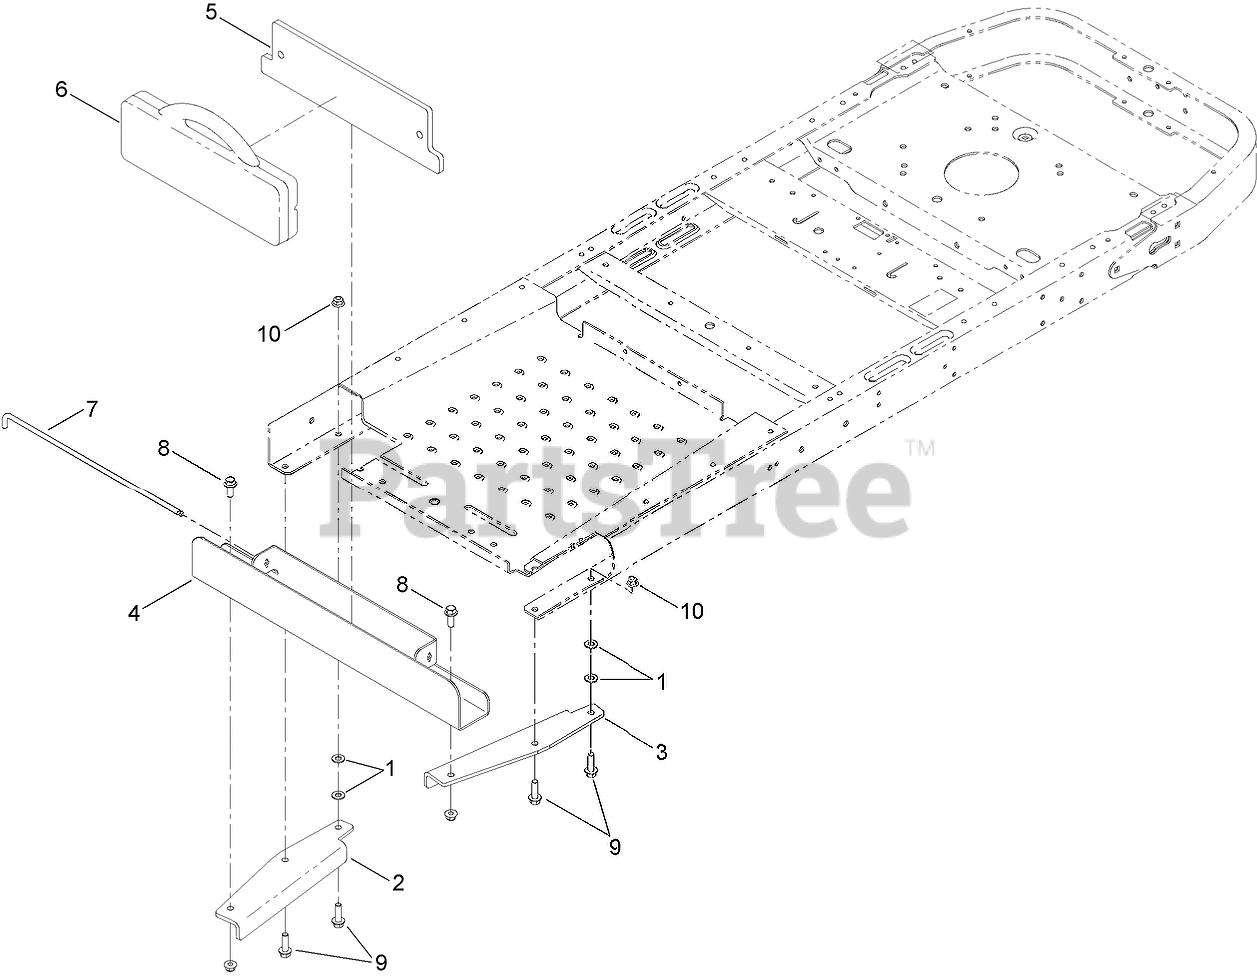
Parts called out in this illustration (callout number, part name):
1	WASHER-FLAT
2	BRACKET-BAGGER WEIGHT, RH
3	BRACKET-BAGGER WEIGHT, LH
4	CHANNEL-WEIGHT, BAGGER
6	WEIGHT-35 POUND
7	PIN-WEIGHT
8	SCREW-HHF
9	SCREW-HHF
10	NUT-HF, NI
